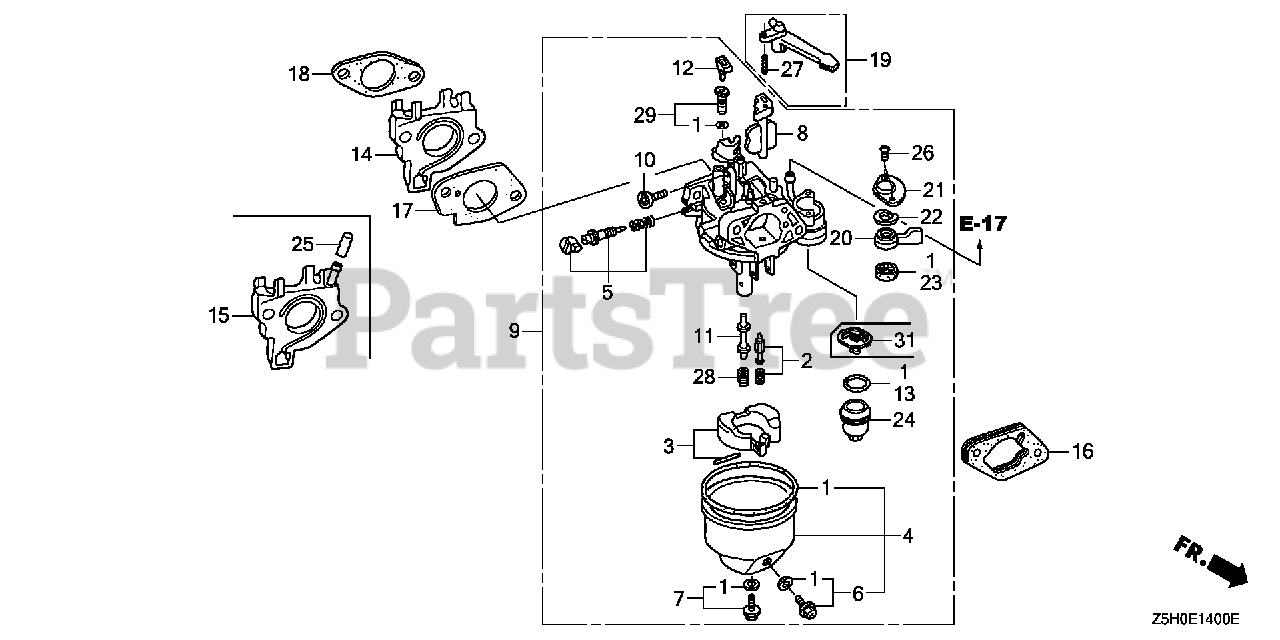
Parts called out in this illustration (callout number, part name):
1	GASKET SET (INCLUDE 16173-001-004) (INCLUDES 16173-001-004)
2	VALVE SET, FLOAT
3	FLOAT SET
4	CHAMBER SET, FLOAT
5	SCREW SET (Honda Code 4219879). (CARBURETOR NO.)
6	SCREW SET, DRAIN (Honda Code 1672187). (CARBURETOR NO.)
7	SCREW SET B
7	SCREW SET
8	CHOKE SET
9	CARBURETOR ASSY. (BE75B B/C)
10	SCREW, THROTTLE STOP
11	NOZZLE, MAIN (CARBURETOR NO.)
12	COLLAR, SET
13	GASKET, FUEL STRAINER CUP
14	INSULATOR, CARBURETOR
16	SPACER, CARBURETOR
17	GASKET, CARBURETOR
18	GASKET, INSULATOR
19	LEVER, CHOKE (STD)
20	LEVER, VALVE
21	PLATE, LEVER SETTING (CARBURETOR NO.)
22	SPRING, PETCOCK LEVER (CARBURETOR NO.)
23	GASKET, VALVE
24	CUP, FUEL STRAINER
26	SCREW, PAN (3X6)
27	PIN, SPRING (2X12)
28	JET, MAIN (#80)
28	JET, MAIN (#82)
28	JET, MAIN (#85) Use up to Engine SN BE81B B.
29	JET SET, PILOT (#40) (ADVENTURE GREEN) (CARBURETOR NO.)
